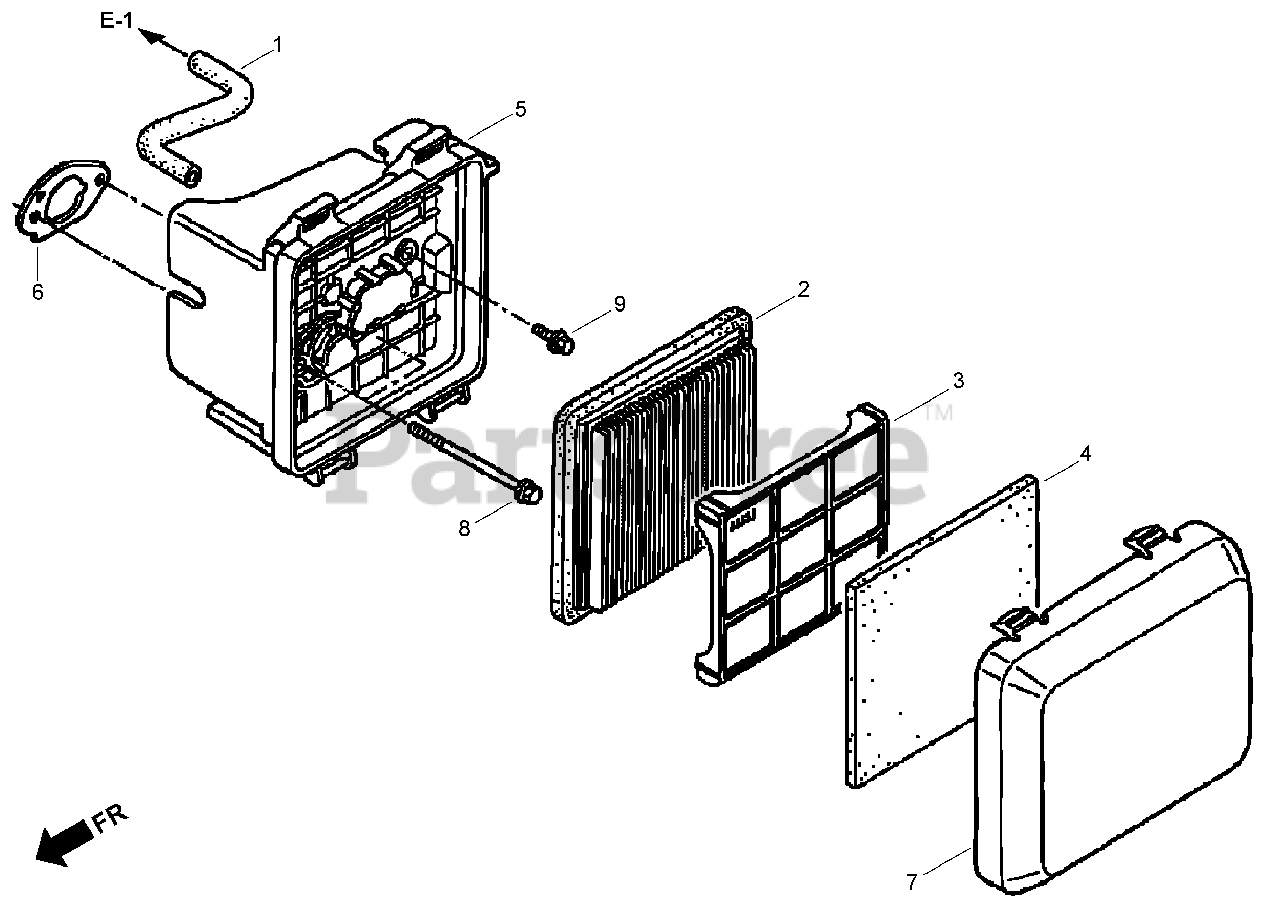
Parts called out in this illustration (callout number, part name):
1	TUBE-BREATHER
2	ELEMENT-CLEANER, AIR
3	GRID-CLEANER, AIR
4	FILTER (OUTER) (WET)
5	AIR CLEANER CASE ASM
6	GASKET-CLEANER, AIR
7	COVER-CLEANER, AIR (DUAL)
8	BOLT-FLANGE (6X86) (C T200)
9	BOLT-FLANGE (6X14)
